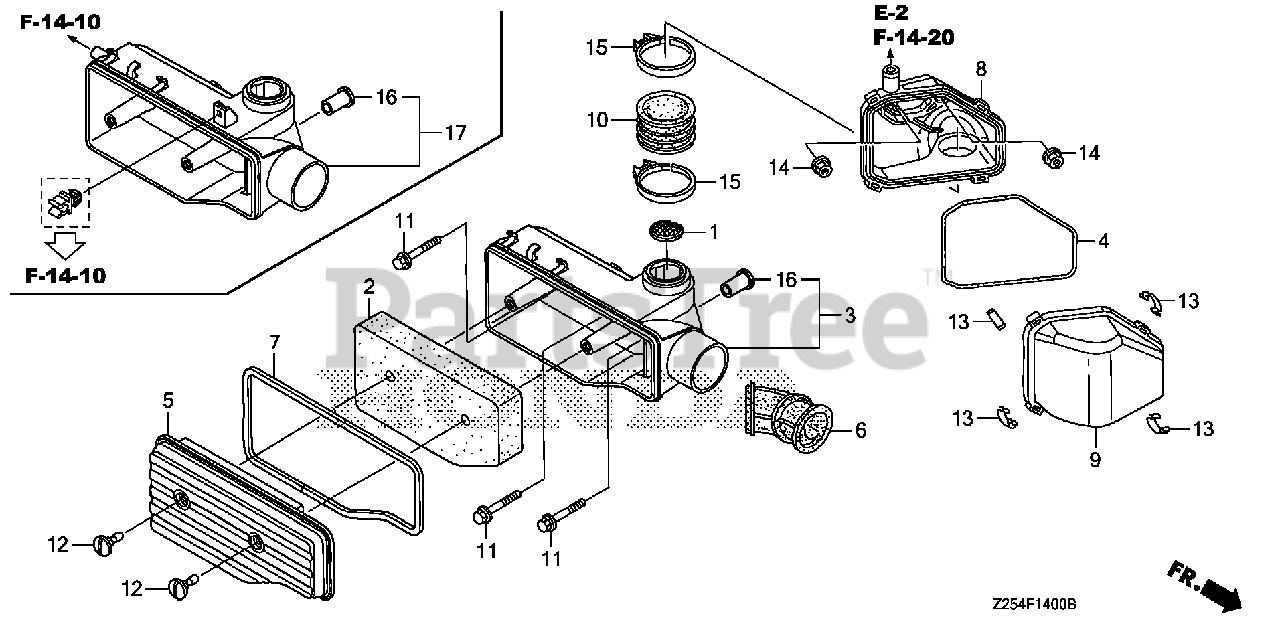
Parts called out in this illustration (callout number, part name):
1	TRAP, FLAME
2	ELEMENT, AIR CLEANER
3	HOUSING, AIR CLEANER
4	SEAL, AIR CLEANER CHAMBER
5	COVER, AIR CLEANER
6	RUBBER, AIR CLEANER
7	SEAL, AIR CLEANER COVER
8	HOUSING, AIR CLEANER CHAMBER
9	COVER, AIR CLEANER CHAMBER
10	TUBE, AIR CLEANER CONNECTING
11	BOLT, FLANGE (6X23)
12	BOLT, AIR CLEANER COVER (- SCREW)
13	CLAMP, CASE
14	NUT, FLANGE (6MM)
15	BAND, AIR CLEANER CONNECTING TUBE (54)
16	COLLAR, FAN COVER (Honda Code 5580527). (N/A: SEE ASSEMBLY)
